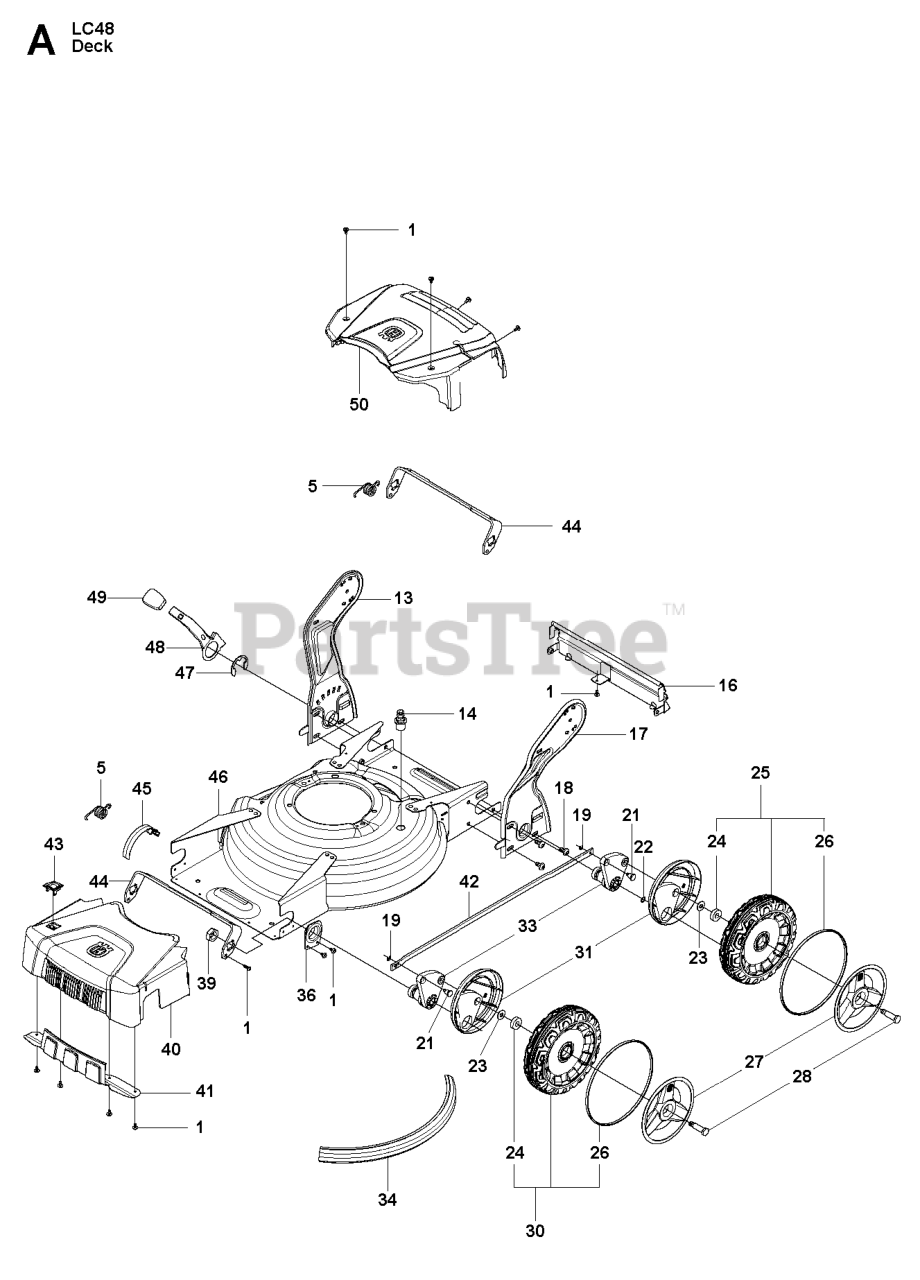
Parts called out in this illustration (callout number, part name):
1	SCREW ITXPANTT M5X10 ZPB (A00
4	BELT WRAPPED V-BELT Z 29.5
19	FASTENER
24	BALL BEARING
46	CHASSIS 48S A009 PAINTED
50	REAR COVER A009-2
